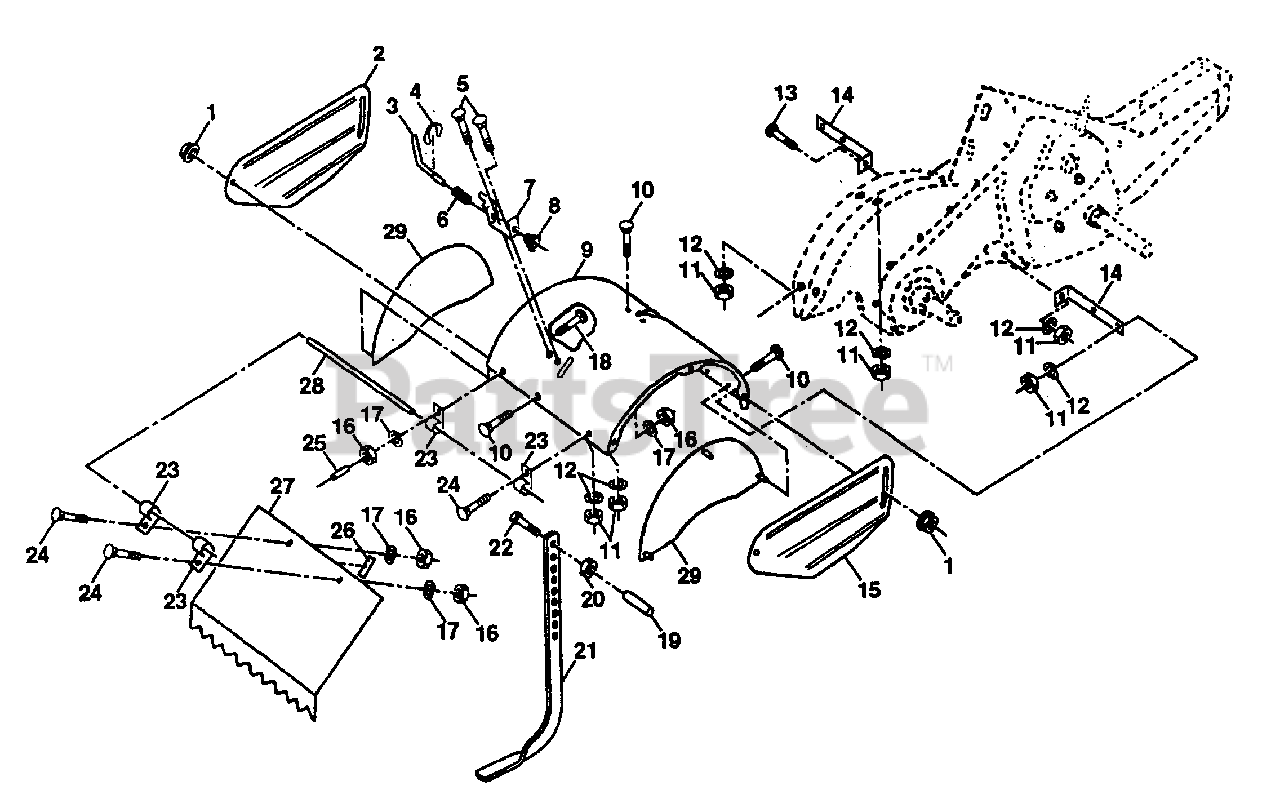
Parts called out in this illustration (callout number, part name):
1	Nut, Flange 5/16-18 (AYP part number)
2	Shield, Side, Outer L. H. (AYP part number)
3	Pin, Stake, Depth (AYP part number)
4	Ring, Klip (AYP part number)
5	Bolt, Carriage 5/16-18 x 1 (AYP part number)
6	Spring (AYP part number)
7	Bracket, Latch (AYP part number)
8	Spring, Depth Stake (AYP part number)
9	Shield, Tine (AYP part number)
10	Bolt, Carriage 5/16-18 x 3/4 Gr 5
11	Nut, Hex 5/16-18 (AYP part number)
12	Washer, Lock 5/16 (AYP part number)
13	Bolt, Carriage 5/16-18 x 1-1/4 (AYP part number)
14	Bracket, Shield Tine (AYP part number)
15	Shield, Side, Outer R.H. (AYP part number)
16	Nut, Hex 1/4-20 (AYP part number)
17	Washer, Lock 1/4 (AYP part number)
18	Bolt, Carriage 1/4-20 x 1-1/4 Gr. 5 (AYP part number)
19	Grip (AYP part number)
20	Nut, Hex 3/8-16 (AYP part number)
21	Stake, Depth (AYP part number)
22	Bolt, Hex 3/8-16 x 2 (AYP part number)
23	Hinge (AYP part number)
24	Bolt, Carriage 1/4-20 x 1/2 Gr. 5 (AYP part number)
25	Cap, Vinyl (AYP part number)
26	Pad, Idler (AYP part number)
27	Shield, Leveling (AYP part number)
28	Pin, Hinge (AYP part number)
29	Shield, Side (AYP part number)
